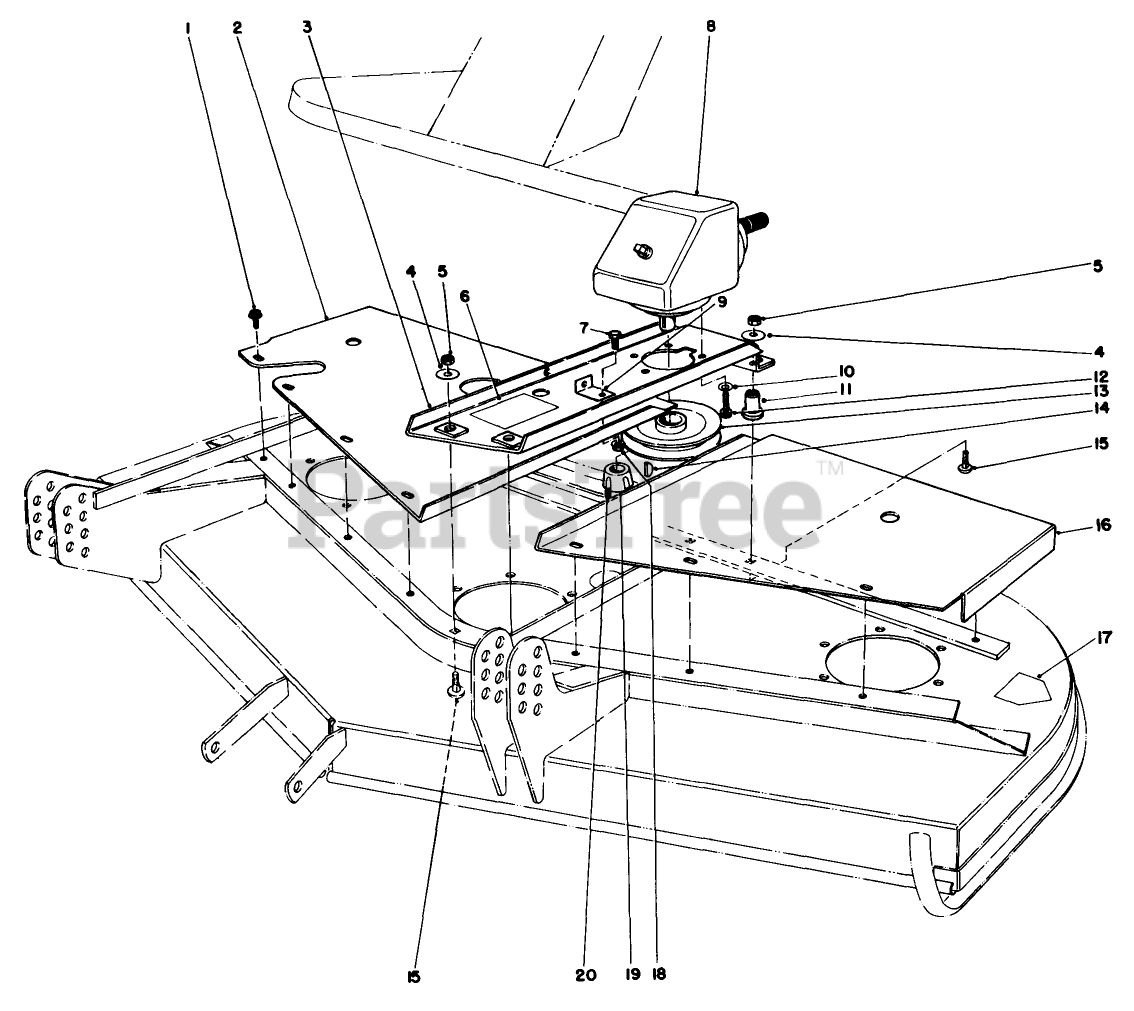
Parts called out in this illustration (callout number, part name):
1	SCREW-HHFTF
2	RH COVER WA *R
4	WASHER
5	NUT-LOCK, SIDE
6	DECAL
7	SCREW-HH
9	EXTENSION BRKT *R
10	WASHER-LOCK
11	MOUNT
12	SCREW-HSH
13	GEARBOX PULLEY ASM
14	KEY-WOODRUFF
15	SCREW-CARR
16	LH COVER WA *R
17	DECAL-DANGER
18	NUT-HF
19	BUSHING-LOCK, TAPER
20	SCREW-SET, HSH
